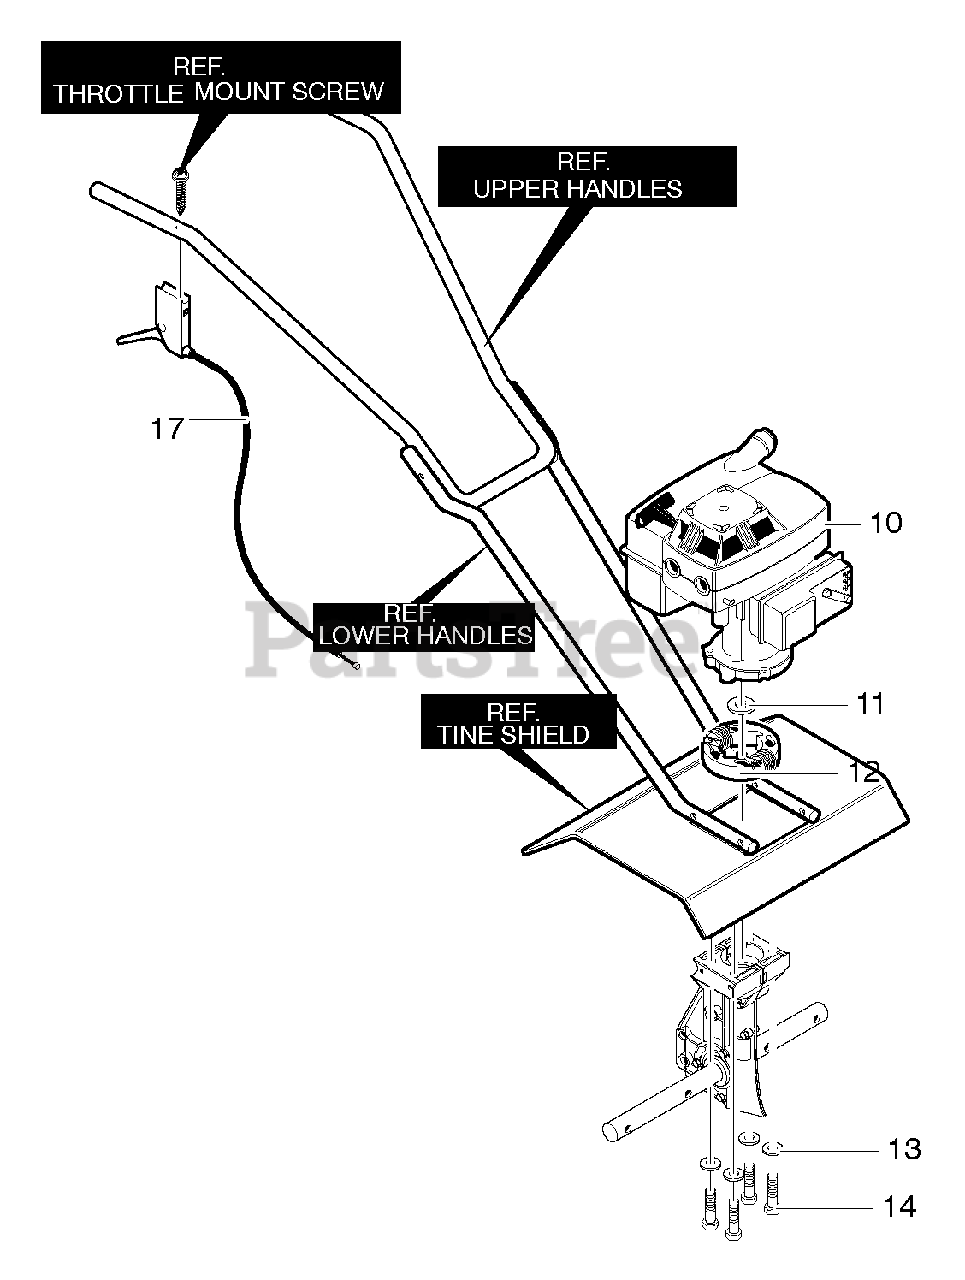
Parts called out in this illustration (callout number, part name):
10	Engine
11	Flat washer
13	Washer, Reg
14	Screw
17	Cable, Throttle
